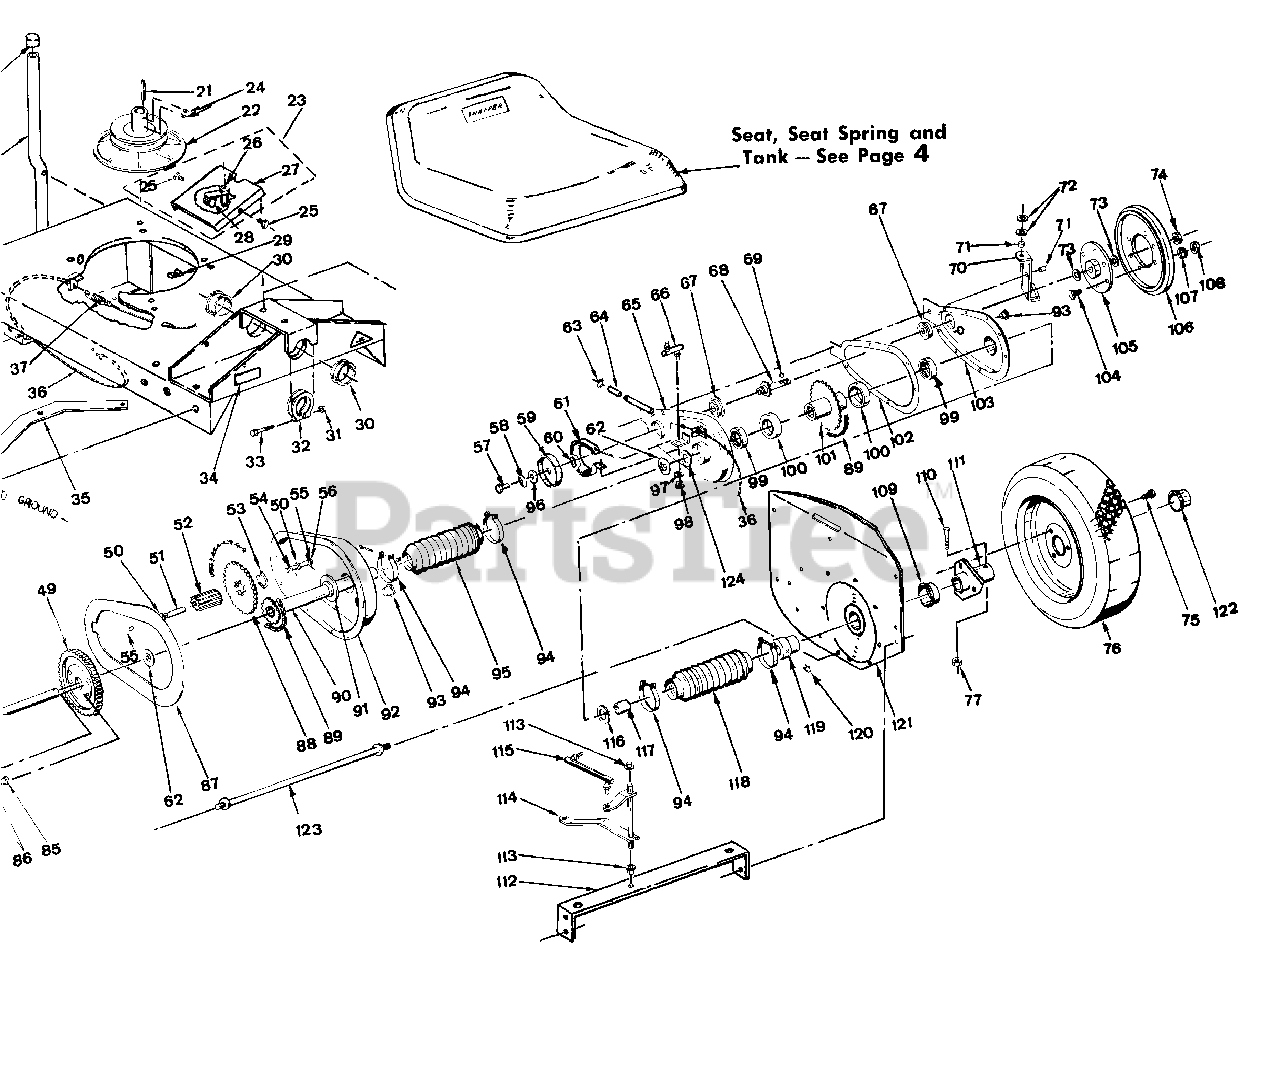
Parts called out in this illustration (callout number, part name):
21	Key
22	Drive Disc Assembly
23	Switch Panel Assembly
24	3/8-16 x 3/8 Set Screw
25	1/4-20 x 3/8 HWST
26	Pushbutton Start Switch
27	PANEL, Switch (NLA, use 38240 and drill .641" switch hole)
28	INTERLOCK, B & S
29	Washer
30	Grommet
31	5/16-24 Flange Lock Nut
32	Tube Clamp
33	5/16-24 x 2 1/2 Hex Hd Cap Screw
34	Name Plate
35	Hitch Plate
36	Brake Cable Housing
37	Brake Spring
49	Gear, 63T, 10P
50	5/16 Belleville Washer
51	Spacer
52	Gear, 11T, 10P
53	Retaining Ring
54	Idler Bolt
55	O-RING, 5/16"
56	5/16 Internal Tooth Lock Washer
57	3/8-24 x 1/2 Hex Hd Cap Screw
58	Clutch Washer
59	Brake Drum
60	Belleville Washer
61	Auxiliary Brake Band
62	Flange Washer
63	Retaining Ring
64	Roller
65	Cover - Right Hand
66	Shift Link, Short
67	Bearing
68	Sprocket and Shaft
69	Woodruff Key
70	Brake Lever Assembly
71	Split Spacer
72	Washer
73	Belleville Washer
74	5/8-18 Hex Lock Nut
75	Lug Bolt
76	Wheel and Tire Assembly
77	5/16-24 Lock Nut, GR. 5
85	Pinion Spacer
86	Gear, 12 Tooth, 12 Pitch
87	Gasket
88	Sprocket
89	Chain
90	ASSEMBLY, Drive Hex Tube
91	Washer
92	Case
93	Plastic Plug
94	Boot Clamp
95	BOOT, Oil Seal
96	Brake Drum Washer
97	5/16 Lock Washer
98	NUT, 5/16-24 Hex
99	Needle Bearing
100	Nylon Thrust washer
101	Hub & Sprocket Structure
102	Gasket
103	Cover, L.H.
104	5/16-18 x 3/4 Carr. Bolt
105	Hub
106	Driven Disc (R/B 7018782)
107	5/16 Lock Washer
109	CAP, Seal L.H. 3/4"
110	Axle Bolt, L.H.
111	Hub, L.H.
112	Cross Brace
113	Nylon Bearing
114	Shift Arm
115	Shift Link, Long
116	Shim Washer
117	Bearing Spacer
118	Boot
119	Bearing
120	Grease Fitting
121	Fender, L.H.
122	Hub Cap
123	Tie Rod
124	Nylon Washer
